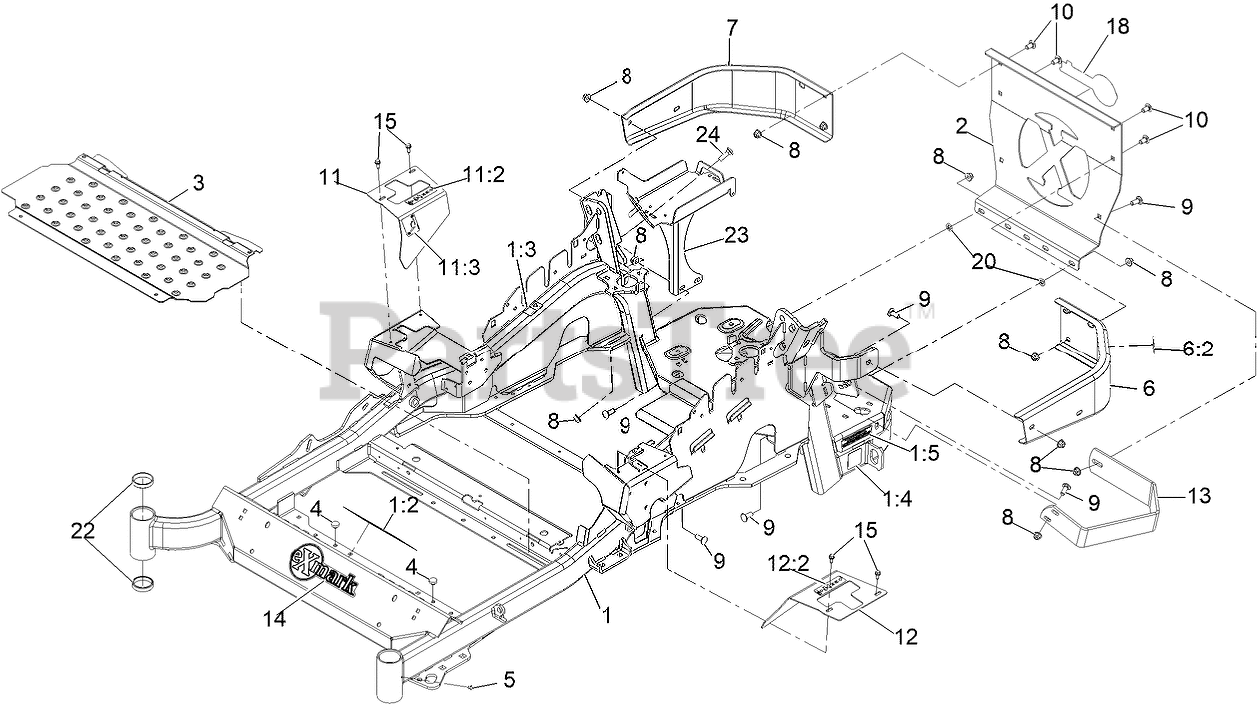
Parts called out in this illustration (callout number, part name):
1	Mainframe Service ASM - 48/52
1:2	DECAL-DANGER
1:3	DECAL-WARNING
1:4	DECAL-HAZARD, PINCHED FINGER
1:5	DECAL-ARRESTOR, SPARK
2	PLATE,REAR GUARD
6	LH BUMPER ASM
6:2	DECAL-WARNING
7	BUMPER-RH
8	NUT-HF, NI
9	SCREW-CARR
10	SCREW-CARR
11	RH MOTION CONTROL COVER ASM
11:2	DECAL-CONTROL, MOTION
11:3	DECAL-PARK BRAKE, CE
12	LH MOTION CONTROL COVER ASM
12:2	DECAL-CONTROL, MOTION
13	GUARD-MUFFLER
14	DECAL-EXMARK
15	SCREW-HWH
18	DECAL, EXMARK LOGO
20	NUT-PUSH
22	CUP-BEARING
23	BATTERY MOUNT ASM
24	BOLT-CARR
